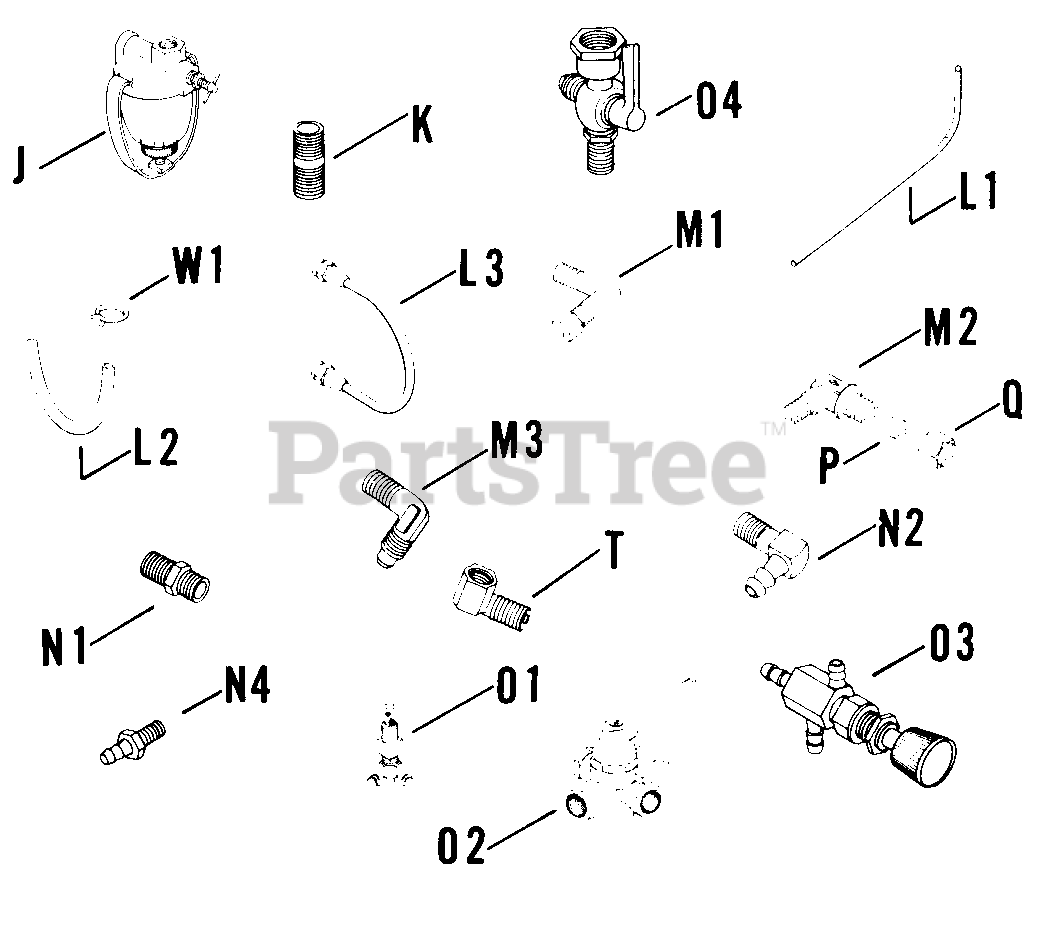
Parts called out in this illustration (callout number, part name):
J	KIT - USE 25 755 22
K	NIPPLE, PIPE 1/8 X 3/4 USE 25 136 23-S
L2	LINE - USE X-810-15
N2	HOSE - USE 25 155 02
